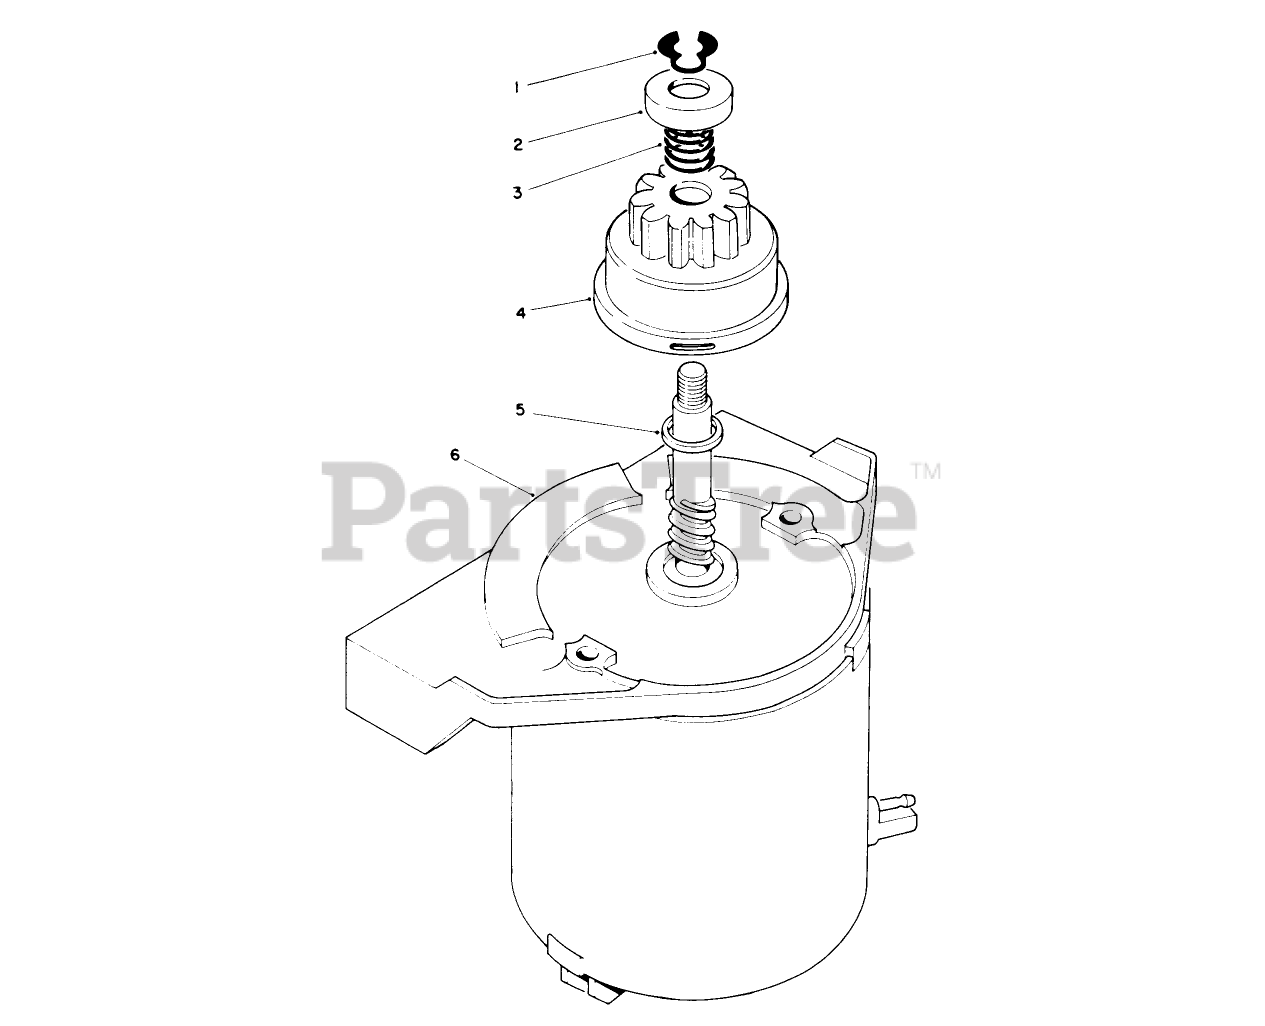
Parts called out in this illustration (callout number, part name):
1	RING-RETAINING
2	PINION STOP
3	COMPRESSION SPRING
4	PINION ASM
5	SPACER
6	END FRAME ASSY, MOTOR
